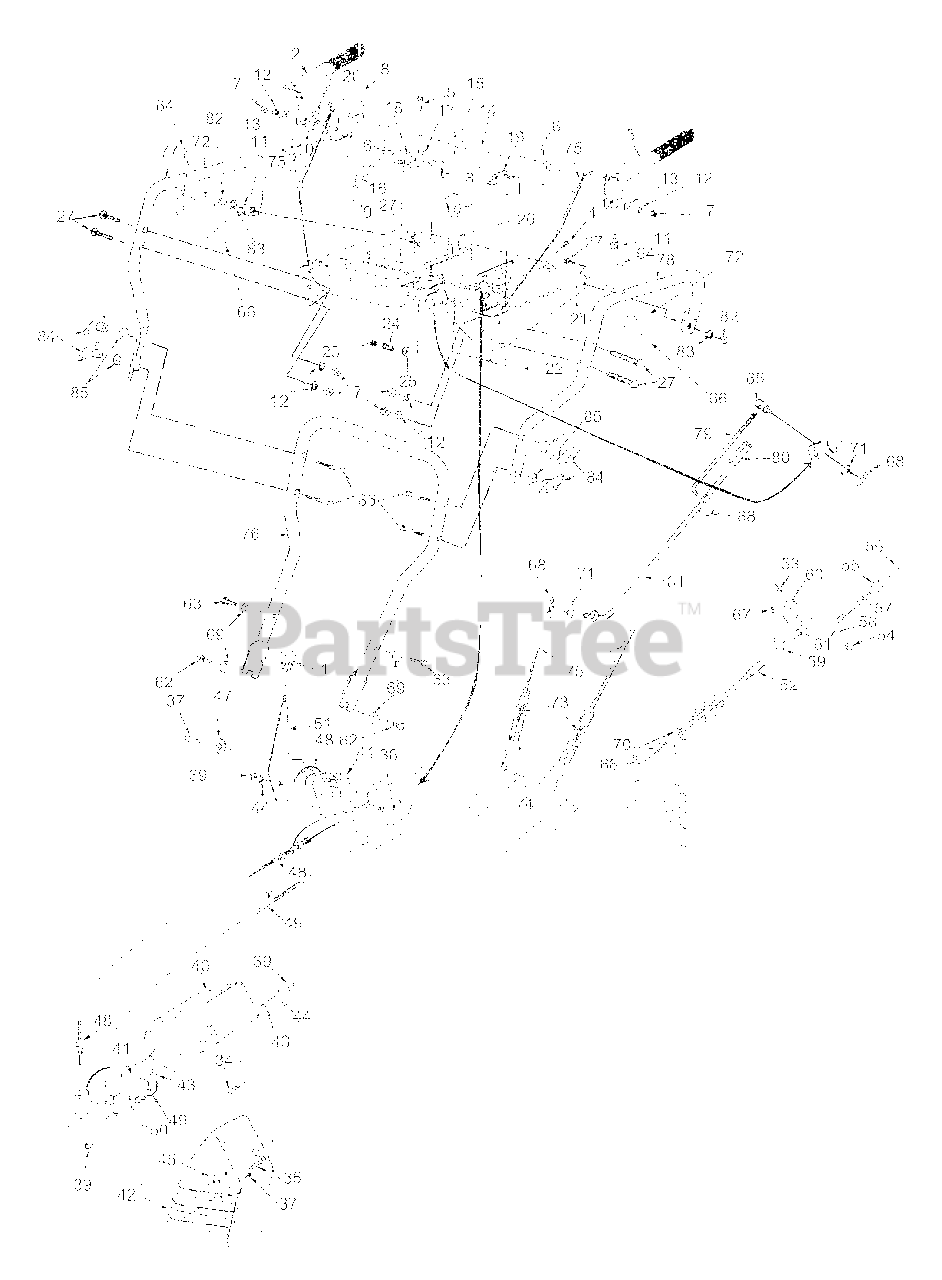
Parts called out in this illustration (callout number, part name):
1	Shift Knob
2	Engage Handle Le Blk Dip Rh
3	Engage Handle Lf Blk Dip Lh
4	Pan Head B-tapp Scr #10 x .5
5	Hwhd Sf-tap Scr 1/4-20 x 1/2 Lg.
6	Clevis Pin .31 Dia x 1.0
7	Nut Hex 5/16-18 Gd 5
8	Cot-pin 3/32 Dia x 1.0
9	Comp Spring .36 Dia x 1.0 Lg
10	Spring Torsion .44 ID
11	Rubber Bumper .63 Dia
12	Lock Washer 5/16
13	Wsher Spcl. .345 I.D. x .72 OD
14	Cam Rod
15	Clutch Lock Cam
16	Clutch Lock Pawl
17	Supt Brkt 5/8 L.H.
18	Supt Brkt 5/8 R.H.
20	Supt Brkt 3/8 R.H.
22	Scr Hex Cap 3/8-24 x 1.5 Gd 5
23	Hex Ins L-nut 3/8-24
24	Compression Spring .39 ID x .88
25	Bell Wash .40 ID x .88 OD x .06
26	Shift Handle
27	Carriage Bolt 5/16-18 x 1.75
34	Carriage Bolt 5/16-18 x 1.00
35	Carriage Bolt 5/16-18 x 1.75
36	Hex Scr 5/16-18 x 1.5
37	HWHD B Tapp Scr 1/4 x 5/8 Lg.
39	Hex Ins L-nut 5/16-18
40	6" Upper Chute Remote Tilt
41	Chute Tilt Cable Guide
42	6" Lower Chute Remote Tilt
43	Chute Pivot Spacer
44	Fl-wash .344 ID x .88 OD x .063
45	Flt Wshr .344 x 1.125 x .125
47	Contoured Washer
48	Chute Control Cable 66"
49	Chute Control Cable 66" W/clip
51	Chute Tilt Handle
52	Lower Chute Directional Control
53	Hex Scr 1/4-20 x .75 Lg Gd5
54	Hex Nut 1/4-20
55	Chute Directional Control Knob
56	Push Cap 3/8 Palnut #375011
57	Flat Washer .38 ID x .60 OD x .033
58	Bell Wash .26 ID x .75 OD x .06T
59	Upper Chute Directional Control
60	Brkt chute directional control
61	Plastic Bushing .380 ID
62	Hex Scr 3/8-16 x .75
63	Hex Scr 3/8-16 x 1.75
64	Scr Oval C/sunk #10-24 x 1.75
65	Adjustment Ferrule
66	#10-24 Flat Weld Nut
67	Internal Cot-pin 1/2 Dia
68	Inter Cot-pin 5/16 Dia
69	Bell Wash .4 ID x .88 OD x .06
70	Fl-wash .406 ID x .74 OD x .063
71	Fl-wash Sae .34 x .68 x .062
72	Trigger Ass'y Steer
73	Hex Ins L-nut 1/4-20
74	Extension Spring
75	Cable Clutch Drive
79	Upper Shift Rod 5/16 x 10.57
80	2 Pc Shift Rod Connector
81	Lower Shift Rod 3/8 x 14.75
82	Hex Nut 1/4-20
83	Bell Wash .26 ID x .75 OD x .06T
84	Wingnut
85	Bell Wash .345 ID x .88 OD x .060
86	Carriage Bolt 5/16-18 x 2.5
